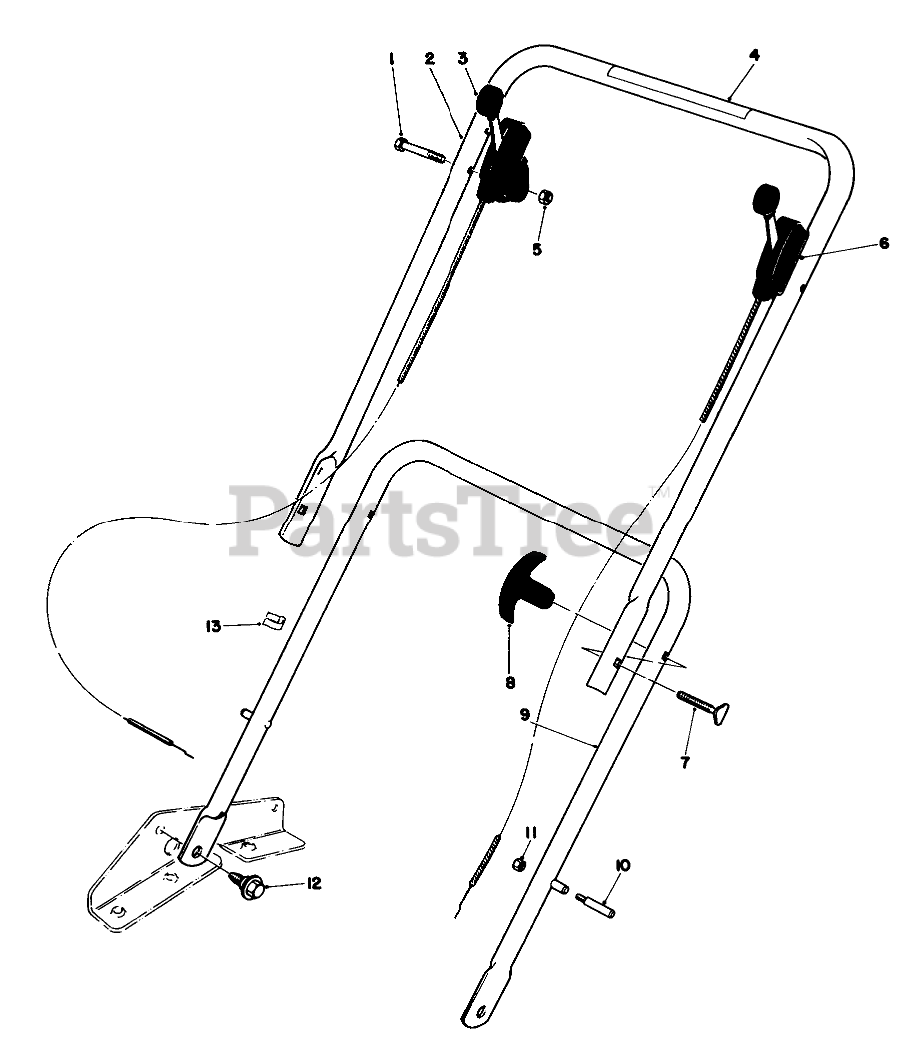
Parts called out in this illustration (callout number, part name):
1	SCREW-HH
2	Upper Handle
3	Throttle Control
4	Decal
5	NUT-LOCK
6	Traction Control
7	HANDLE SCREW
9	LOWER HANDLE ASM SP
10	HANDLE PIN
11	Nut
12	SCREW-SHOULDER
